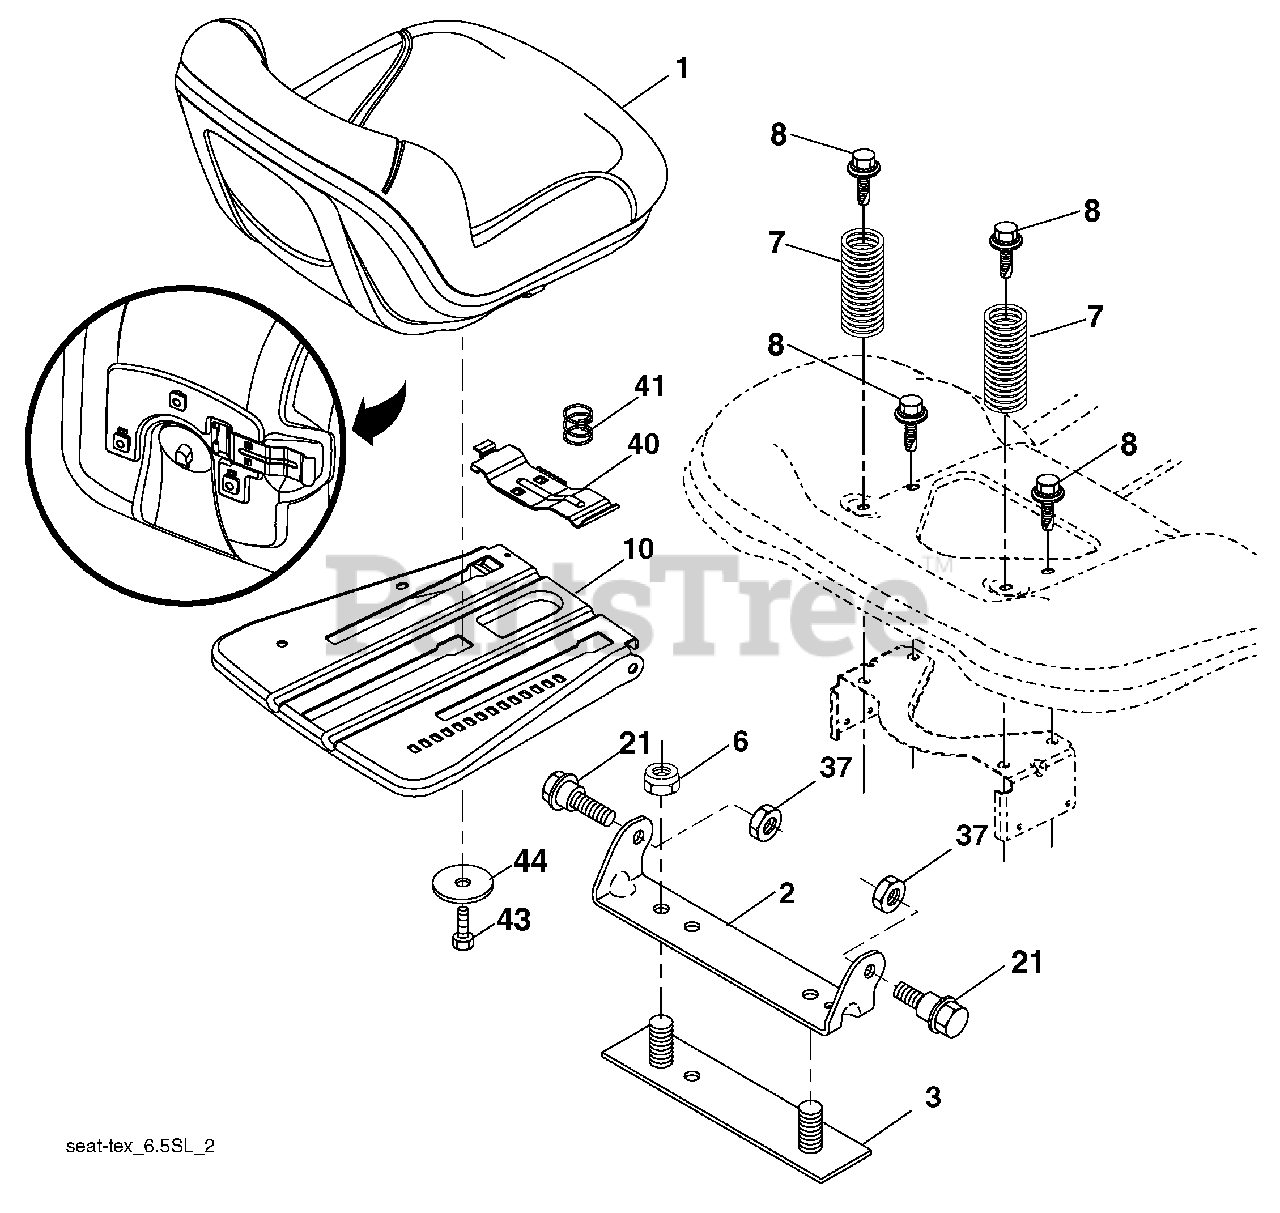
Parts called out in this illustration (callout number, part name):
1	Seat
2	Bracket Pivot Fender
3	Strap, Asm Fender
6	Nut, Lock w/Ins. 3/8-16 unc
7	Spring, Seat Cprsn
8	Bolt 5/16-18 unc x 3/4 w/Sems
10	Pan, Seat
21	Bolt, Shoulder 5/16-18
37	Nut, Lock 5/16-18 unc
40	Handle Slide Seat
41	Spring Latch Seat
43	Bolt 3/8-16 x 3/4
44	Washer 13/32 x 2-3/8 x 12 Ga.
